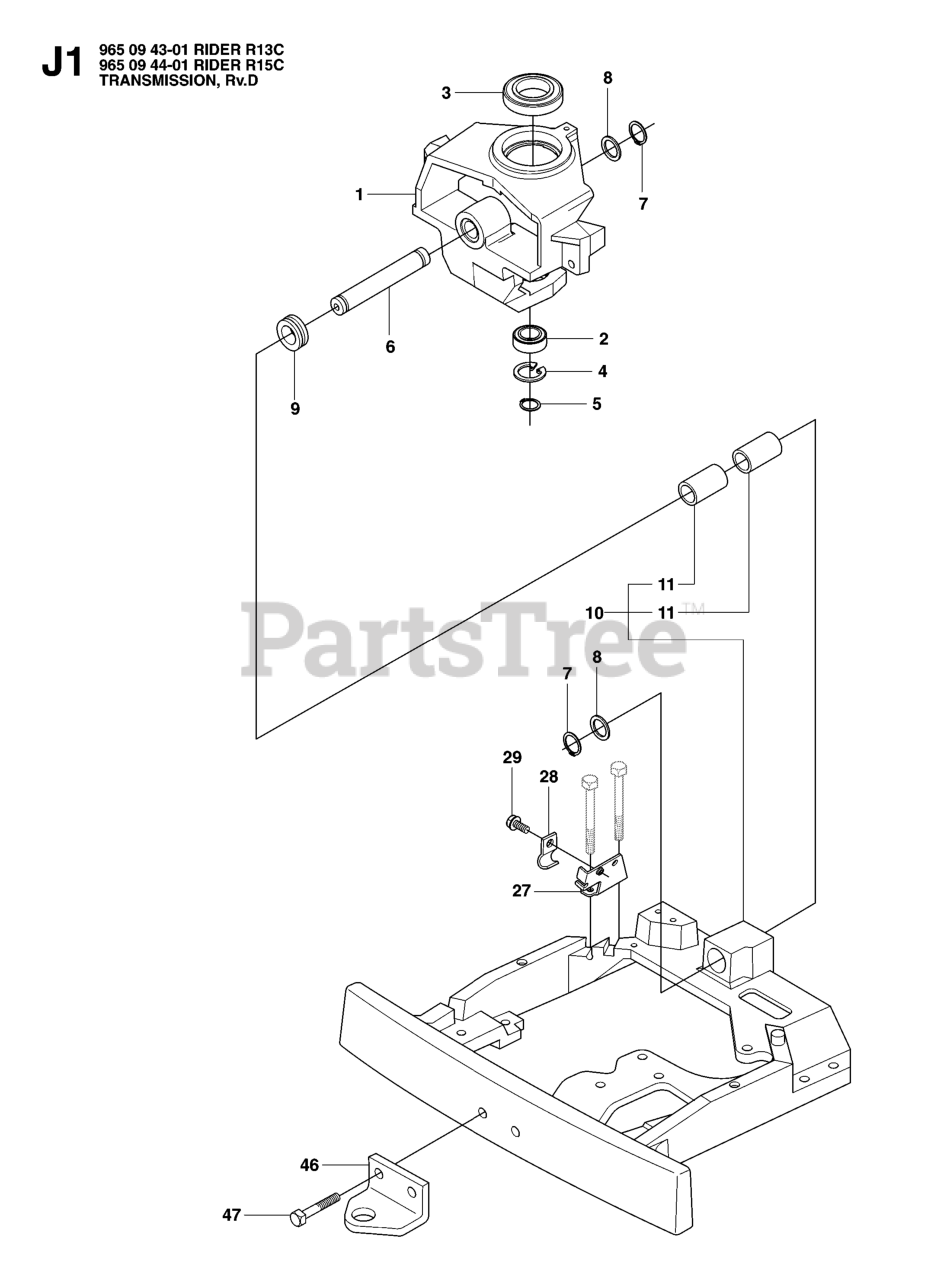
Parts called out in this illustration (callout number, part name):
2	Ball Bearing 6005-2rs
3	BALL BEARING 6010 2RS1
4	CIRCLIP SGH 47
5	RETAINING RING SGA 25
7	RETAINING RING SGA 25
47	Screw M10x25
